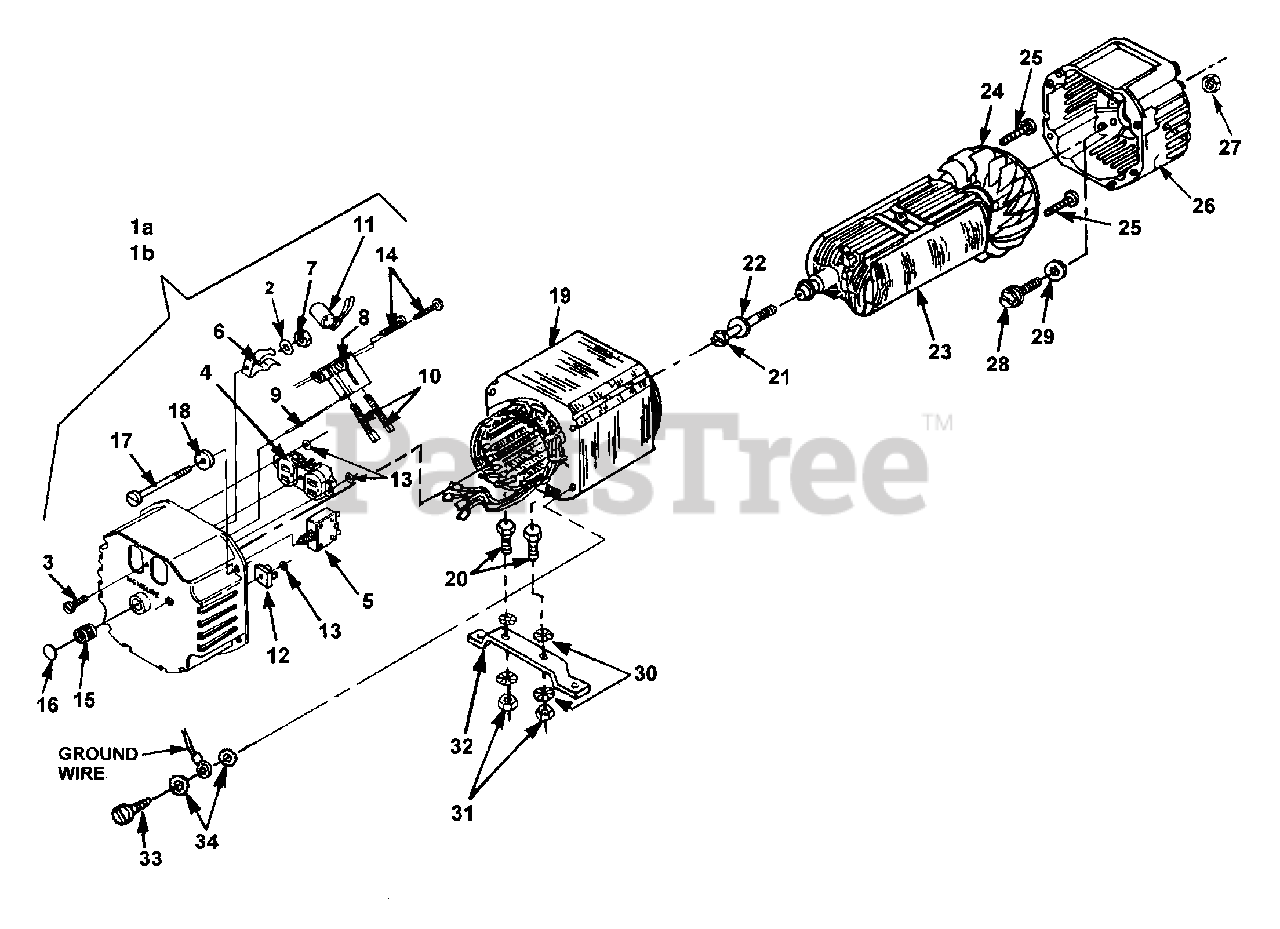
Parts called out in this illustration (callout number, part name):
1A	COMPLETE BRUSH HEAD
1B	COMPLETE BRUSH HEAD (CSA)
2	WASHER-Lock (ext.)
3	SCREW-Mach. Pan Hd. (6-32 X 1/2")
4	RECEPTACLE-Duplex (Nema 5-15R)
5	BREAKER-Circuit (20 amp.)
6	CLIP-Spring Cap
7	NUT-Hex (6-32)
8	BRUSH HOLDER
10	BRUSH
11	CAPACITOR (w/Lead)
12	RECTIFIER
13	WASHER-Shaft Retention
14	SCREW-Pan Hd. (6-19 X 3/4)
15	BEARING-Needle
16	PLUG-Expansion
17	BOLT-Stator
18	WASHER-Flat (1/4")
19	STATOR
20	SCREW-Hex Hd. (5/16-18 X 3/4")
21	BOLT-Rotor
22	WASHER-Lock (5/16")
24	FAN-Generator
25	SCREW-Pan Hd. (6-19 X 3/4")
26	END BELL
27	NUT-Hex (1/4-20)
28	SCREW-Hex Hd. (5/16-24 X 3/4")
29	WASHER-Lock
30	WASHER-Lock (int./ext.)
31	NUT-Hex (5/16-18)
32	BRACKET-Generator Support
33	SCREW-Taptite (10/24 X 3/4")
34	WASHER-Lock (int./ext.)
